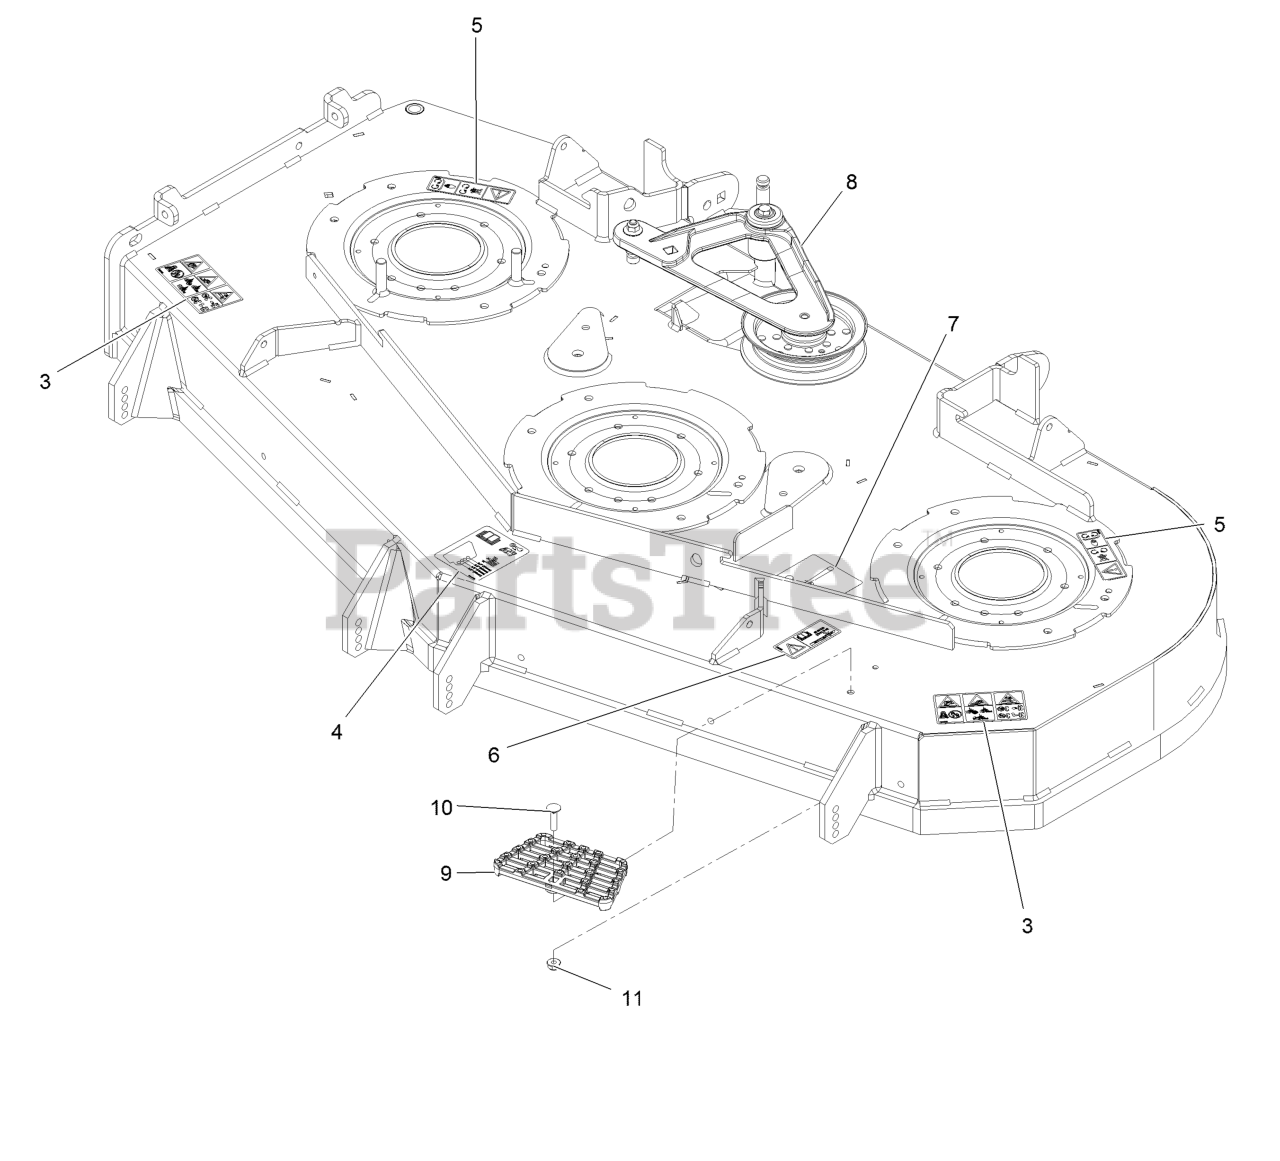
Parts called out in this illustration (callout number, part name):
3	Decal-Danger Thrown Objects
4	Decal-Roller, Anti-Scalp
5	Decal-Cover, Missing
6	Decal-Bolt Torque
7	Decal-Belt Routing
8	Deck Idler ASM
9	Step-Deck
10	Bolt-Carriage 5/16-18 X 1 1/4
11	Nut-Nyloc 5/16-18 Flg
